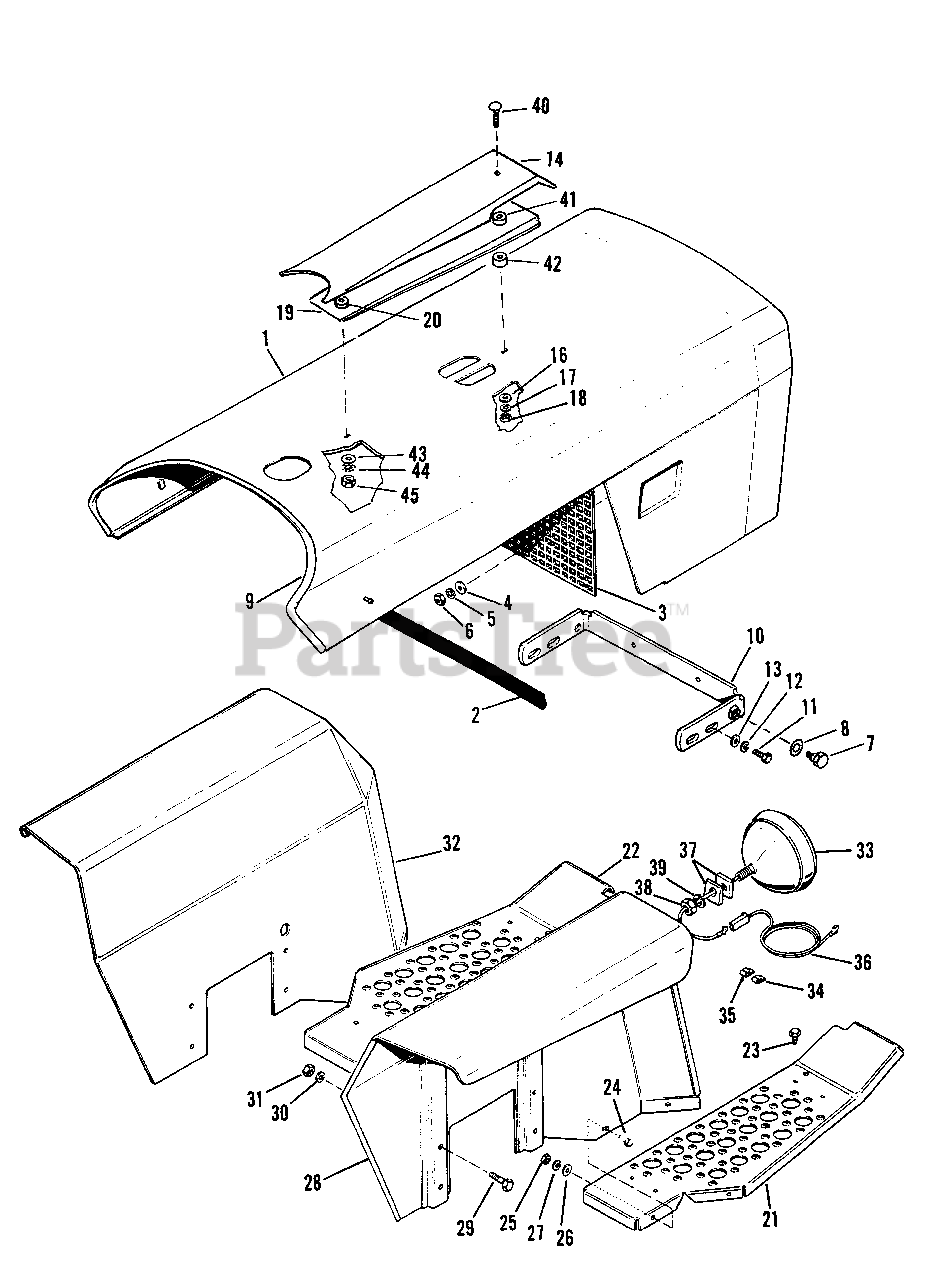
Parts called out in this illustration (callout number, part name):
1	Hood Assembly
5	Shakeproof Lock Washer No. 10
6	Hex Nut, Full, No. 10-24
7	Shoulder Bolt
11	Hex Capscrew, 3/8"-16
12	Plain Washer, 3/8"
13	Lock Washer, 3/8"
14	Scoop Assembly
16	Plain Washer,
17	Lock Washer,
18	Inner Scoop
19	Rubber Washer
21	Platform, R.H.
22	Platform, L.H.
23	Thread Forming Screw 5/16"-18 x 7/8" lg.
24	Thread Forming Screw, 5/16"-18 x 5/8" lg.
25	Hex Nut, Full, 5/16"-18
26	Plain Washer, 1/4"
27	Lock Washer, 5/16"
28	Wheel Guard Assembly, R.H.
29	Hex Capscrew, 3/8"-16 x 1-1/2" lg.
30	Lock Washer, 3/8"
31	Hex Nut, Full, 3/8"-16
32	Wheel Guard Assembly, L.H.
37	Special Washer
38	Hex Nut, Full, 1/2"-13
39	Lock Washer, 1/2"
40	Carriage Bolt, 1/4"-20 x 1-1/2" lg.
41	Rubber Washer
43	Plain Washer, 1/4"
44	Lock Washer, 1/4" Shakeproof
45	Hex Jam Nut, 1/4"-20
